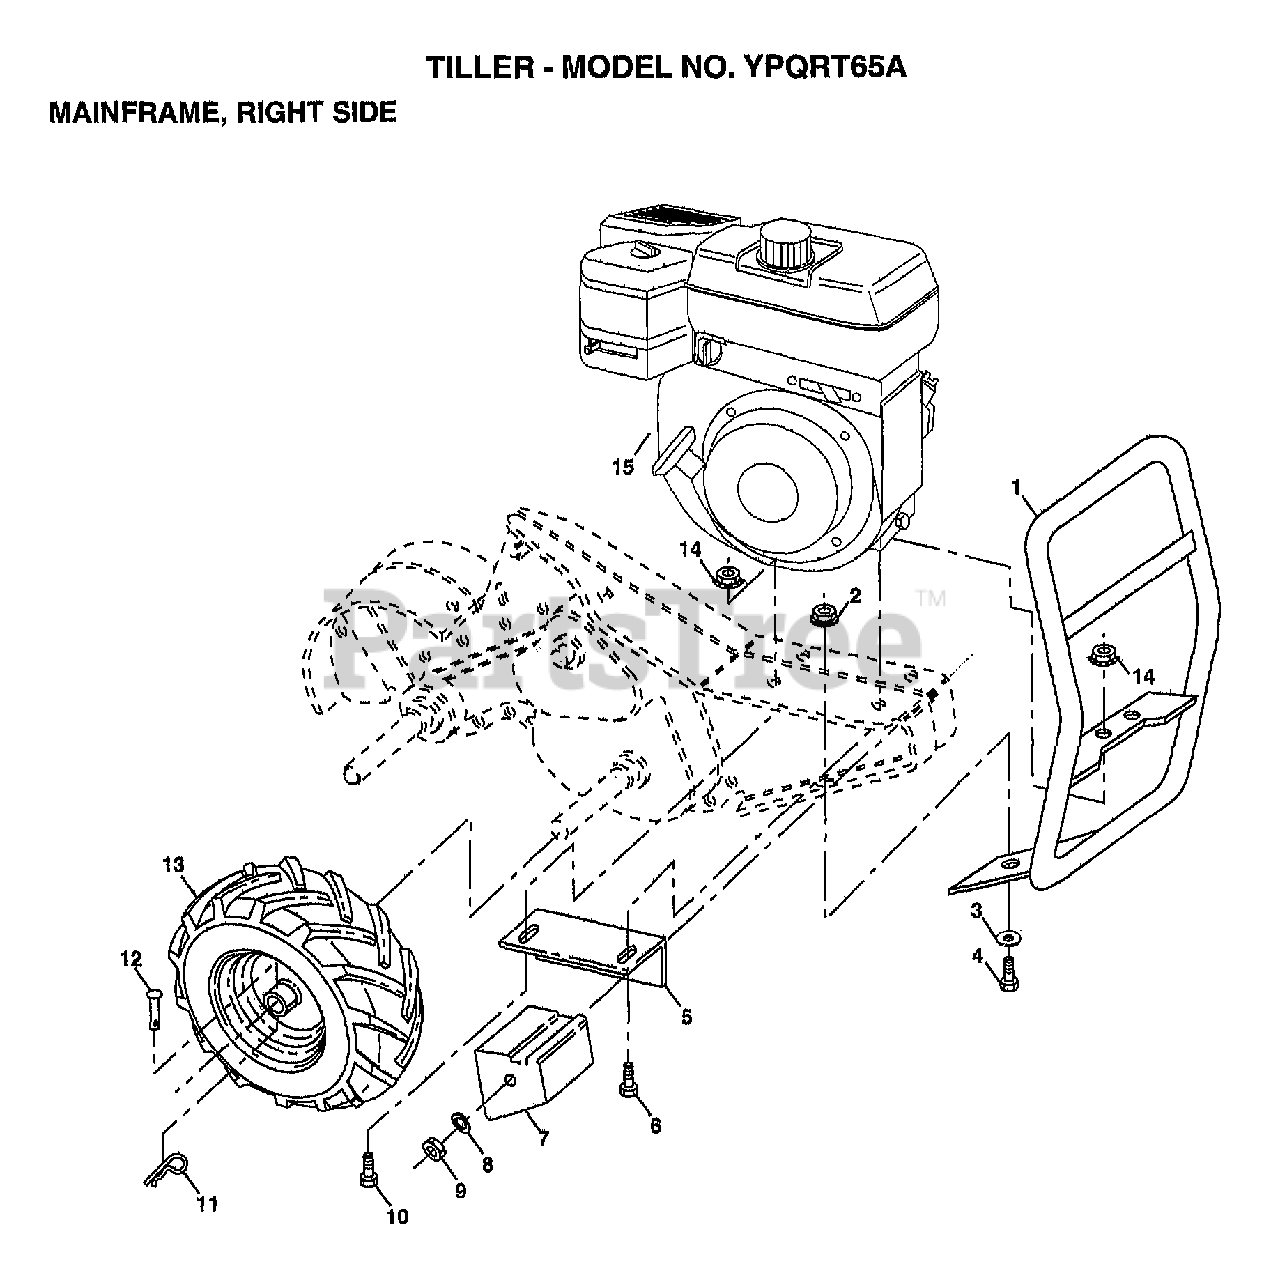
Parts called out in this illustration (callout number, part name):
1	BUMPER ASM.TILLER
2	LOCKNUT TI
3	WASHER
4	BOLT
5	BRACKET RH CRT
6	BOLT
7	COUNTERWEIGHT CRT
8	LOCKWASHER
9	NUT.HEX.3/8-16UNC
10	BOLT.HEX.5/16-1.5
11	RETAINER M
12	RIVET.DRILL.1.75
13	TIRE TI
13	RIM
